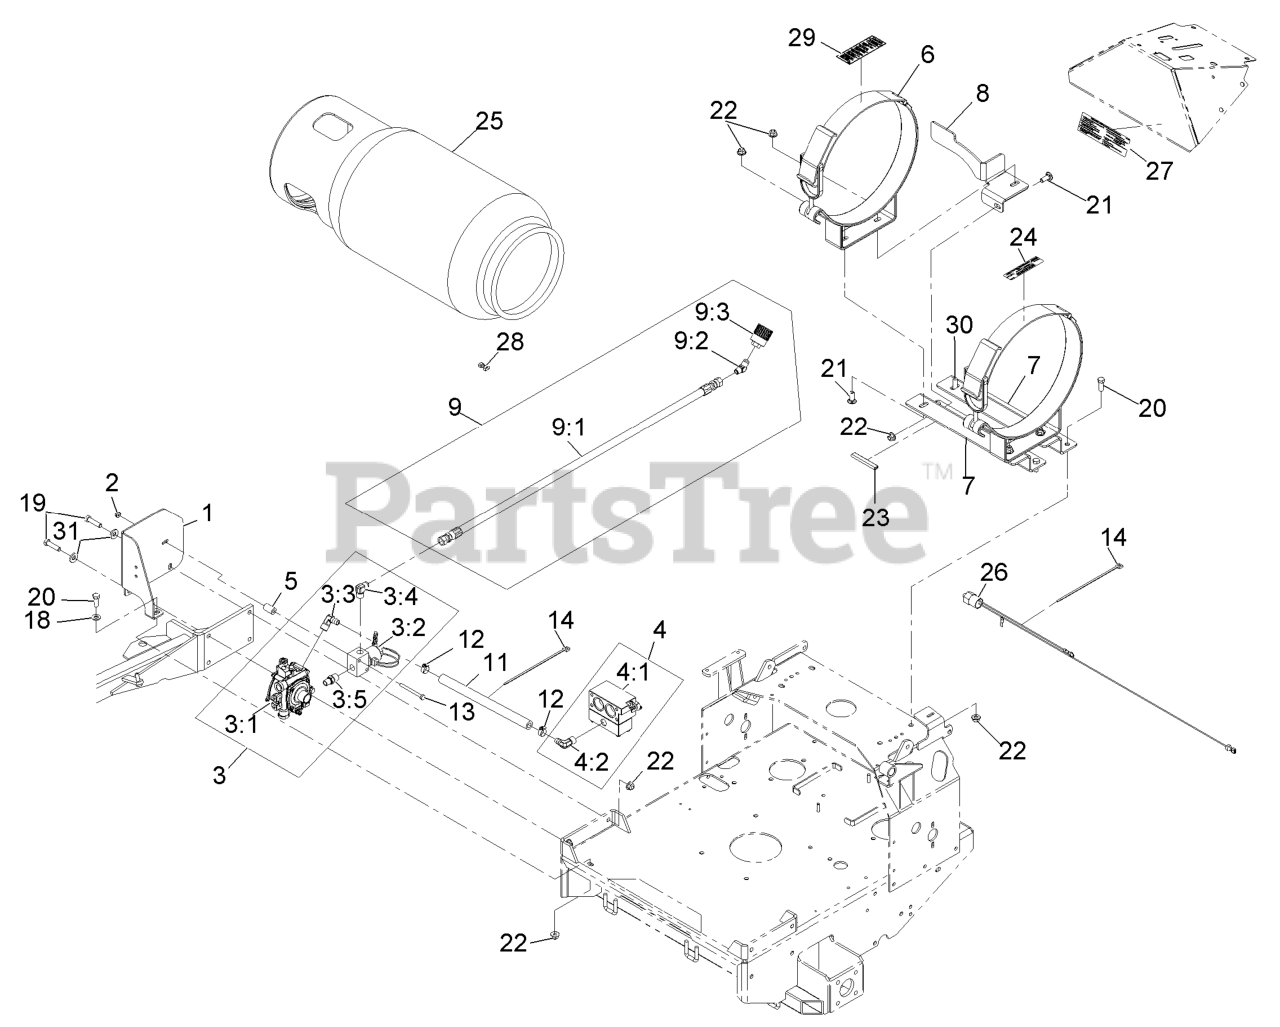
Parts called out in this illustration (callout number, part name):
1	REGULATOR MOUNT-TT
3	Asm, Reg And Shutoff
3:1	Regulator-Lp, T60
3:2	LPG SOLENOID VALVE ASM
3:3	ELBOW-90 DEG
3:4	ELBOW 90,3/8NPT X 3/8SAE
3:5	COUPLING-PIPE, MALE
4	Asm, Mixer
4:1	MIXER,LP FX691V
4:2	ELBOW-90 DEG
6	BRACKETS, LPG TANK - HORI
7	RISER, LPG TANK
8	BRACKET, LPG TANK INDEX
9	Asm, Lpg Fuel Hose
9:2	ELBOW-45 DEG
9:3	CONNECTOR-LPG TANK, LH TH
11	HOSE-LP
12	CLAMP-HOSE
13	SCREW-HH
14	TIE-PLASTIC
18	WASHER-FLAT
19	SCREW-HH
20	SCREW-HH
21	SCREW-CARR
22	NUT-HF, NI
23	STRIP-SEAL
24	DECAL,LPG TANK SPEC HORIZ
25	TANK,LPG 33LB
27	DECAL-TANK REPLACEMENT
28	RECEPTICAL -FEM, .250, IN
29	DECAL-LPG WARNING
30	BOLT-CARR
31	WASHER-BELLEVILLE
